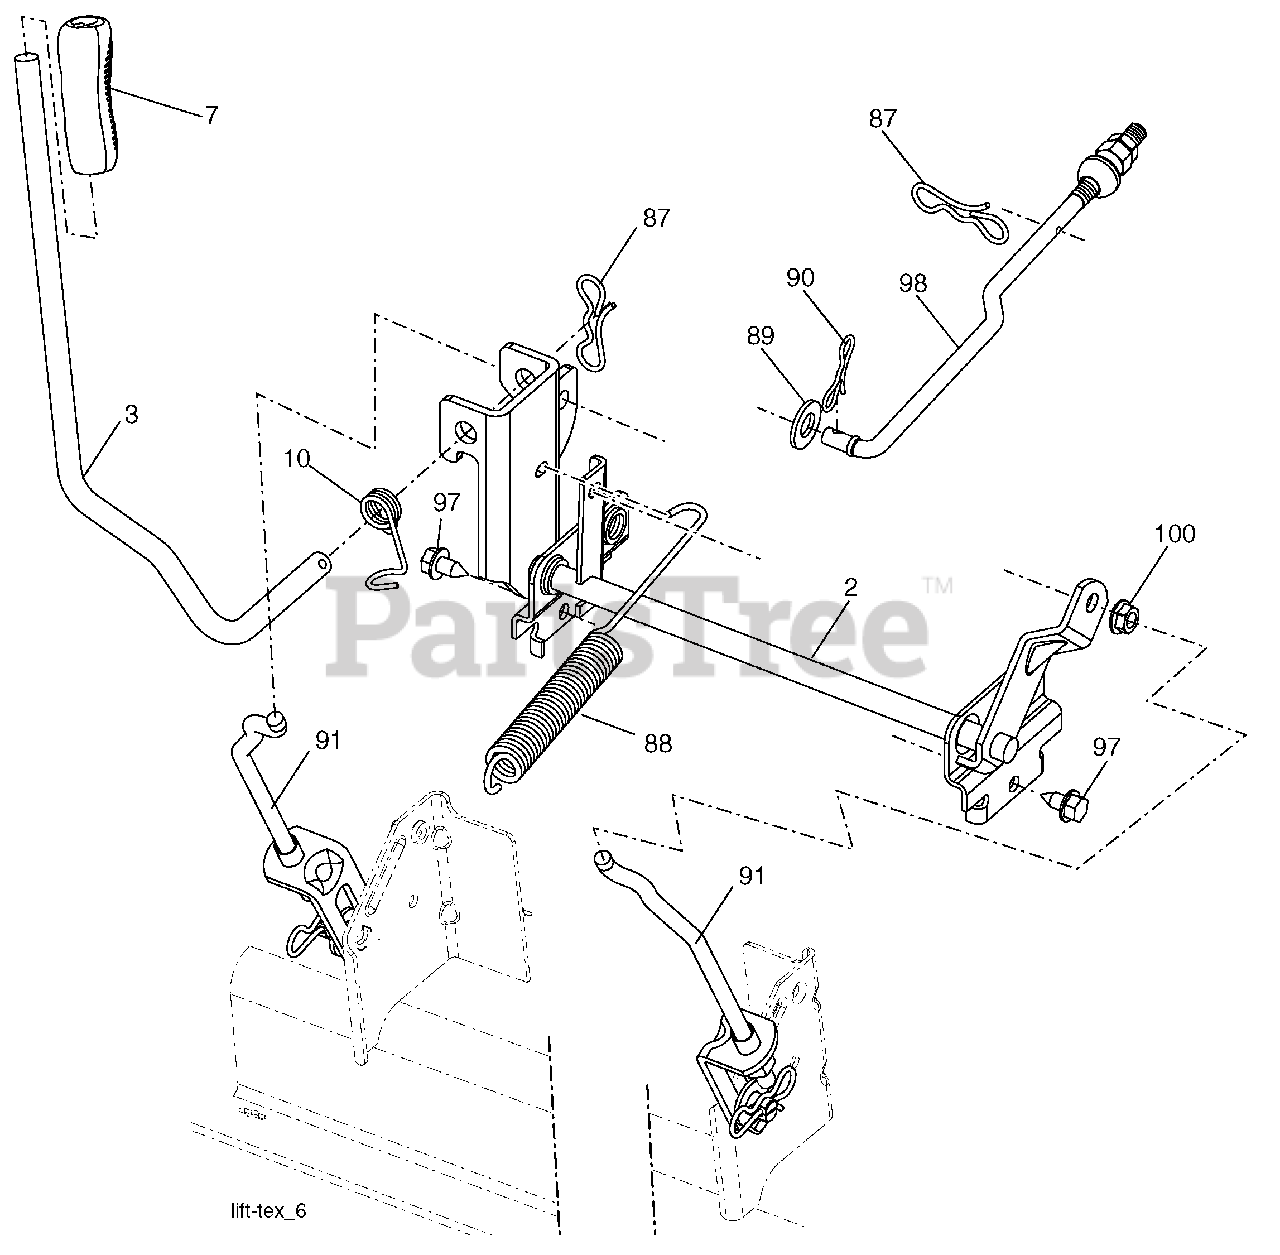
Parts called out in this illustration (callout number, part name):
2	Shaft Asm., Lift
3	Lever Asm., Lift RH
7	Grip, Lever
10	Spring Torsion
87	Pin Cotter 7/16 Bow Tie Lock
88	Spring Lift Assist
89	Washer Clear Zinc
90	Pin Cotter 5/16 Bow Tie Lock
91	Link Lift Susp Mower Rear
97	Screw 3/8-16 x .75
98	Link Lift Susp. Front Mower
100	Nut Centerlock 3/8-16 unc
